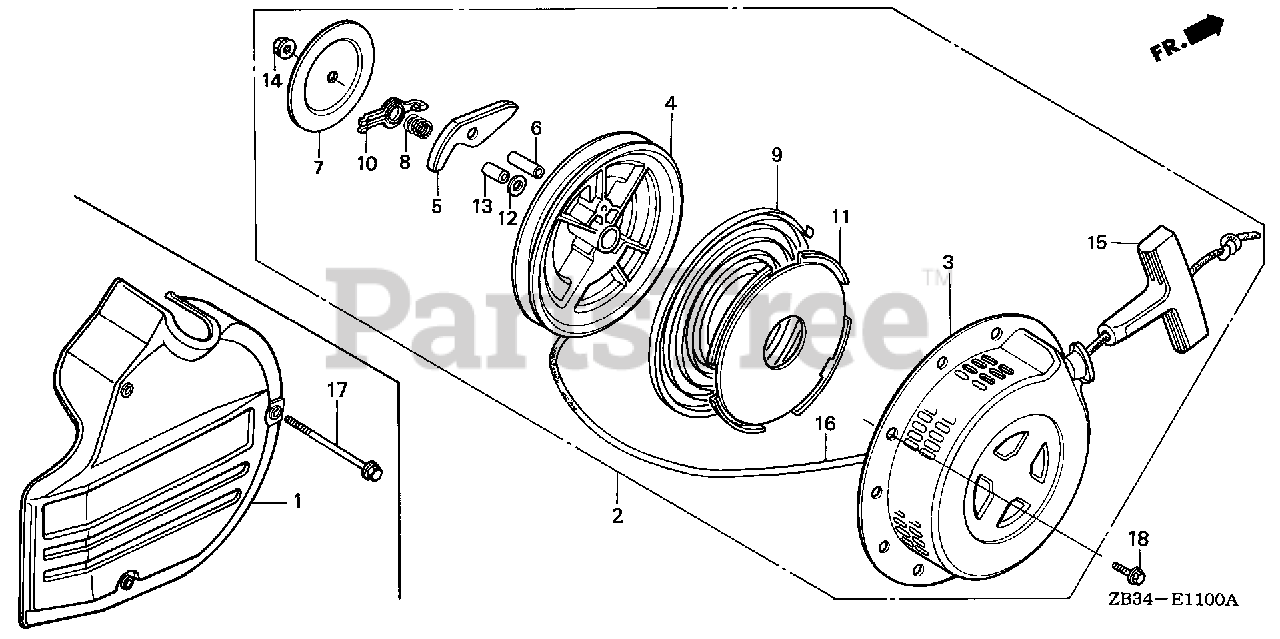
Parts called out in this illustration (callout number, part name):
2	STARTER ASSY., RECOIL *NH1* (BLACK)
3	CASE, RECOIL STARTER *NH16M* (GUN METALLIC BLACK)
3	CASE, RECOIL STARTER *NH1* (BLACK)
4	PULLEY, RECOIL STARTER
5	RATCHET, STARTER
6	PIN, STARTER RATCHET
7	PLATE, FRICTION
8	SPRING, FRICTION
9	SPRING, RECOIL STARTER
10	GUIDE, RATCHET
11	CASE, RECOIL STARTER SPRING
12	WASHER, STARTER
13	SHAFT, SUB
14	NUT
15	KNOB, RECOIL STARTER
16	ROPE, RECOIL STARTER
18	BOLT, FLANGE (6X8)
